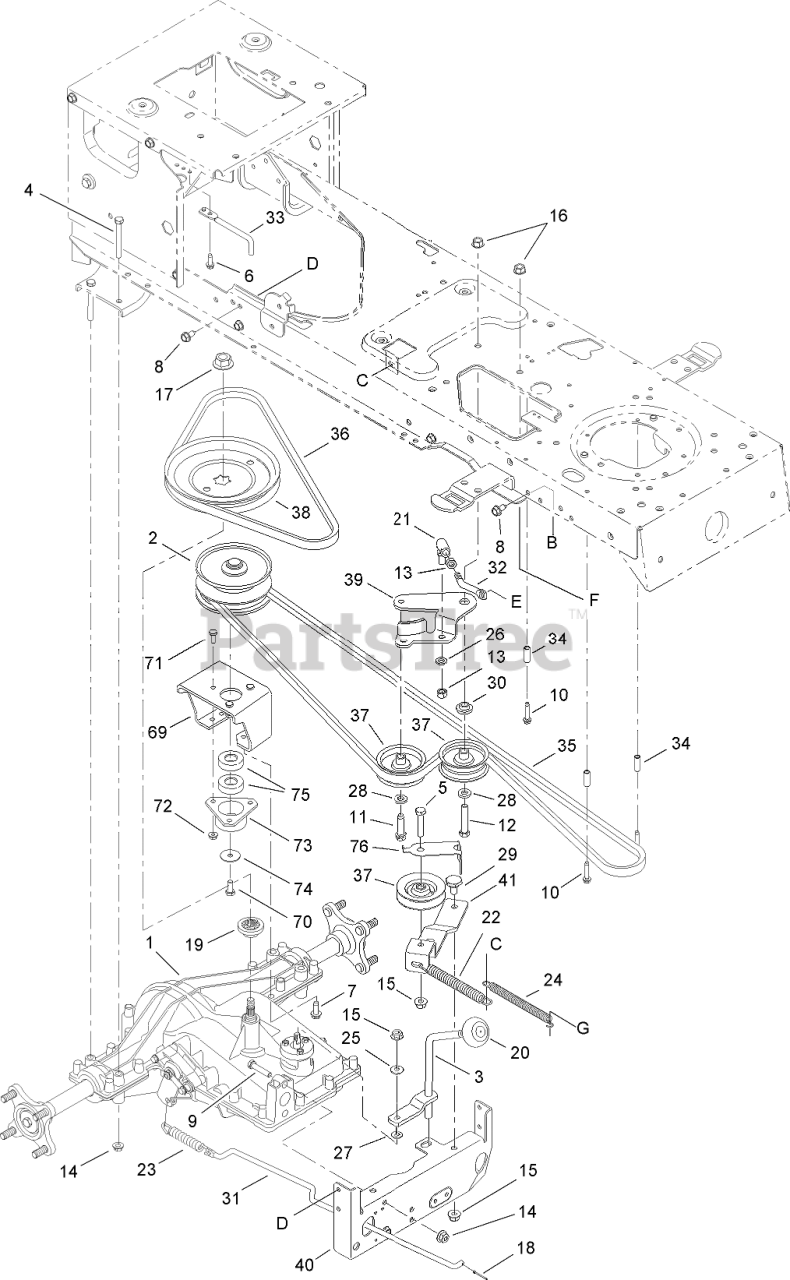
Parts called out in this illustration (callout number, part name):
1	TRANSMISSION ASM
2	VARIABLE SPEED PULLEY ASM
3	SHIFT ROD ASM
4	SCREW-HEX
5	SCREW-HH
6	SCREW-TAP
7	SCREW-HWHTF
8	SCREW-HH, TAP
9	SCREW-HH
10	SCREW-HH
11	SCREW-TAP
12	SCREW-HH
13	NUT-HEX
14	NUT-LOCK, FLANGE
15	NUT-LOCK, FLANGE
16	NUT-LOCK, FLANGE
17	NUT-FLANGE W/HUB
18	PIN-COTTER
19	HUB-PULLEY
20	KNOB-SHIFT
21	BALL JOINT ASM
22	SPRING
23	SPRING-EXTENSION
24	SPRING-EXTENSION
25	WASHER-SPRING
26	WASHER-LOCK
27	WASHER-FLAT
28	WASHER-FLAT
29	BOLT-SHOULDER
30	SPACER-SHOULDER
31	ROD-BRAKE
32	ROD-ADJUSTMENT, IDLER
33	ROD-GUARD, BELT (TRANSMISSION)
34	SPACER
35	BELT-DRIVE, VARIABLE SPEED
36	BELT-DRIVE, TRANSMISSION
37	PULLEY-IDLER, FLAT
38	PULLEY-TRANSMISSION (W/HUBS)
39	BRACKET-IDLER, CENTER DOUBLE
40	BRACKET-TRANSMISSION
41	BRACKET-IDLER
69	BRACKET
70	SCREW-HH
71	SCREW-HH
72	NUT-LOCK, FLANGE
73	CUP-BEARING
74	WASHER-FLAT
75	BEARING-BALL
76	GUIDE-BELT, TRACTION
